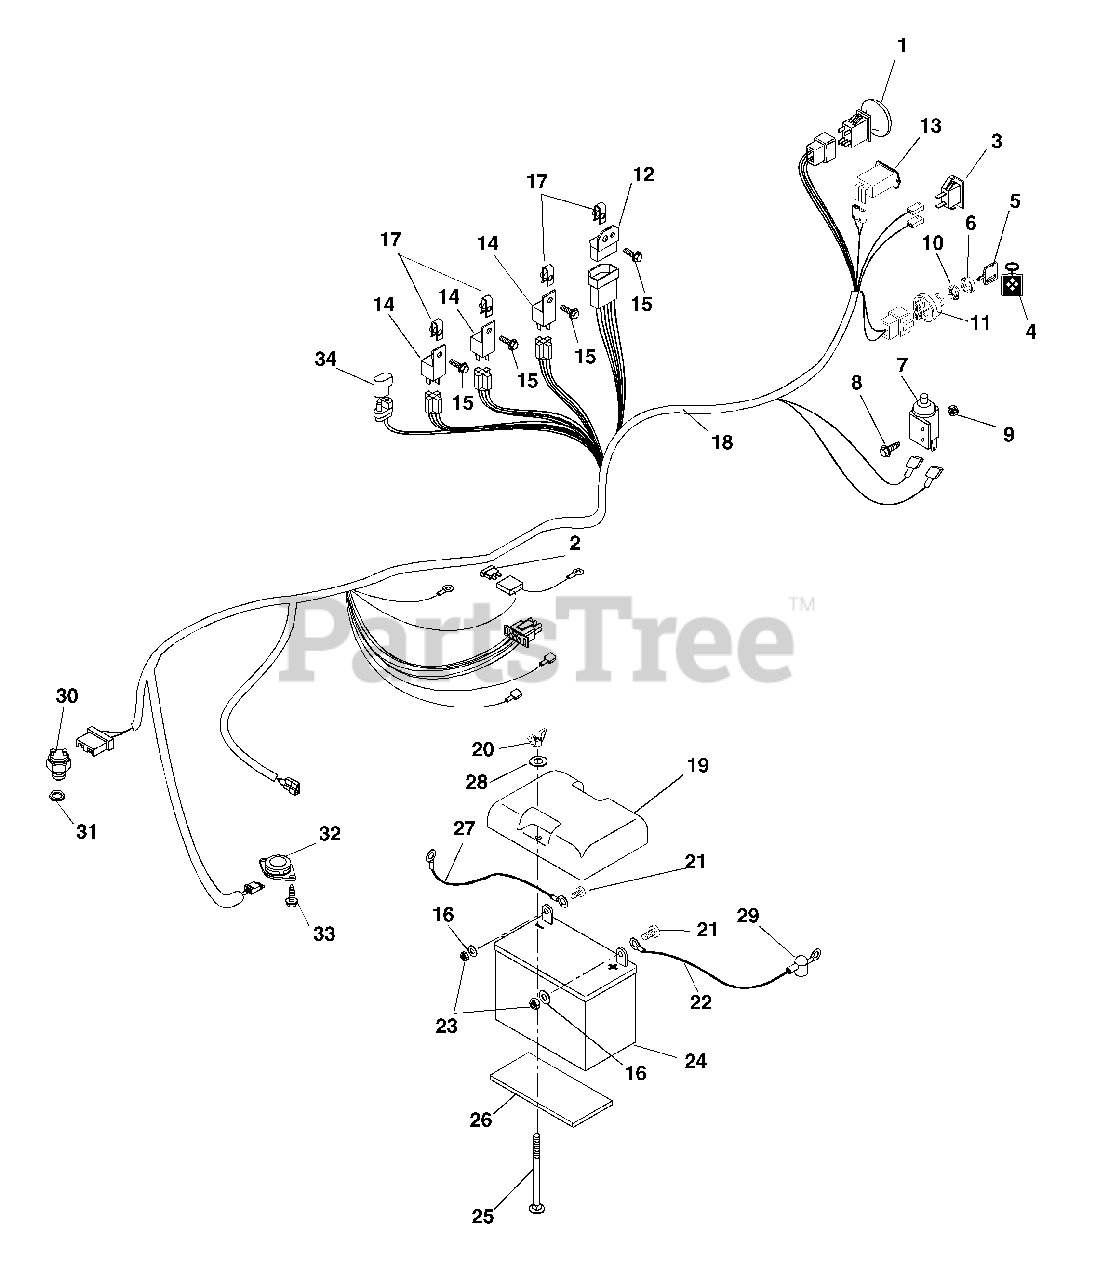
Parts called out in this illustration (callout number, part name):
1	Switch-Clutch with Retainer Ring
2	Fuse, 30 Amp
3	Light-Indicator
4	Key Chain
5	Key with Cap
6	Cap-Ignition Switch
7	Switch-Single Pole (N.O.) with Cover
8	Screw-Machine 10-24 x .50 Hex Washer Head
9	Nut-Locking-Nylon 10-24 with Insert
10	Washer-Lock-Internal .563 x .040
11	Key Switch (018)
11	Key Switch (020)
12	Module, Time Delay
13	Hour Meter
14	Relay
15	Screw-Machine 10-24 x .75 Hex Washer Head
16	Washer-Flat-Steel .281 x .620 x .065
17	Retainer Nut 10-24
18	Harness-Wiring
19	Cover-Battery
20	Nut-Locking-Wing .250-20
21	Bolt-Hex .25-20 x .75 Grade 5
22	Cable-Starter
23	Nut-Hex .25-20
25	Bolt-Round Head Square Neck .25-20 x 7.00 Grade 2
26	Pad, Battery
27	Cable, Negative Battery 35" Long
28	Washer-Flat-Steel .28 x .62 x .065
29	Boot, Eyelet Terminal (018)
30	Switch, Neutral Start (N.C.)
31	Nut-Stamped .56-18
32	Switch, Seat
33	Screw-Tapping 12-24 x .50 Hex Washer Head
34	Molded Diode Plug
35	Nut-Locking-Center .25-20
